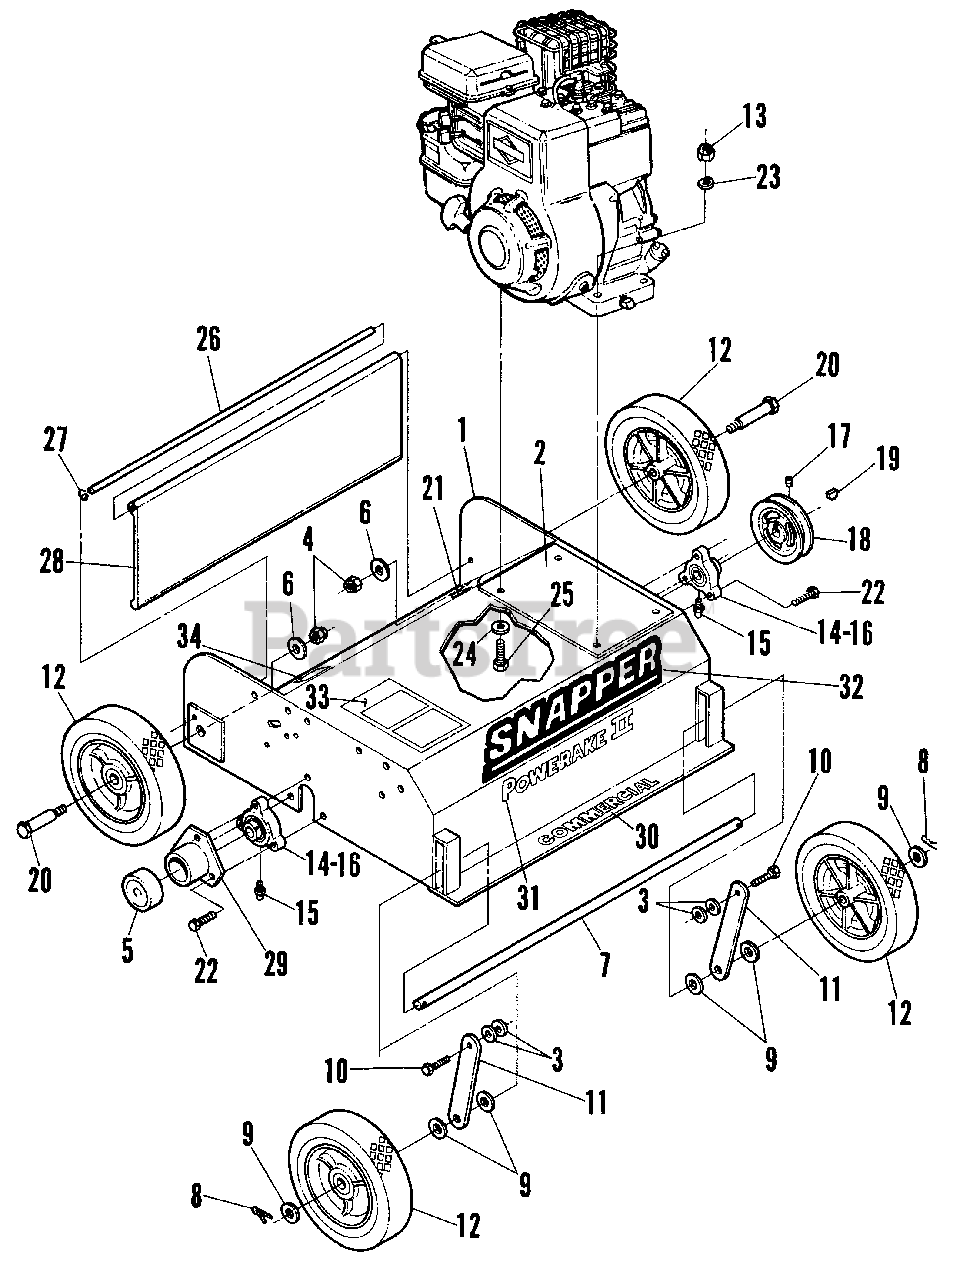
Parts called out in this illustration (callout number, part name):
1	BODY w/Decals
2	ENGINE PAD
3	WASHER, 3/8" Standard Flat
4	NUT, 3/8-16 Hex Nyloc
5	CAP, Shaft Guard
6	WASHER, 1/2" Flat
7	AXLE, Front
8	PIN, 1/8 x 3/4" Cotter
9	WASHER, 1/2" Standard Flat
10	SCREW, 3/8-16 x 1-1/4" Hex Head Cap, Grade 2
11	LIFT ARM
12	WHEEL, 8"
13	NUT, 5/16-18 Hex Nyloc
14	BEARING, Cast Iron Flange
15	FITTING, 1/4-20 Grease
16	SCREW, #10-32 x 1/4" Knurled Cup Point Set
17	SCREW, 5/16-18 x 3/8" Knurled Cup Point Set
18	PULLEY, w/Set Screw (7-6956)
19	KEY, #9/606 Woodruff
20	BOLT, Axle
21	DECAL, Warning
22	BOLT, 5/16-18 x 1-1/4" Hex Head Tap
23	WASHER, 5/16" Split Lock
24	WASHER, 5/16" Standard Flat
25	SCREW, 5/16-18 x 1-3/4" Hex Head Cap, Grade 5
26	ROD, Deflector
27	RING, 5/16" Retaining
28	DEFLECTOR
29	GUARD, Shaft
30	DECAL, Commercial
31	DECAL, Powerake II
32	DECAL, Snapper
33	DECAL, Instructions
34	DECAL, Caution
